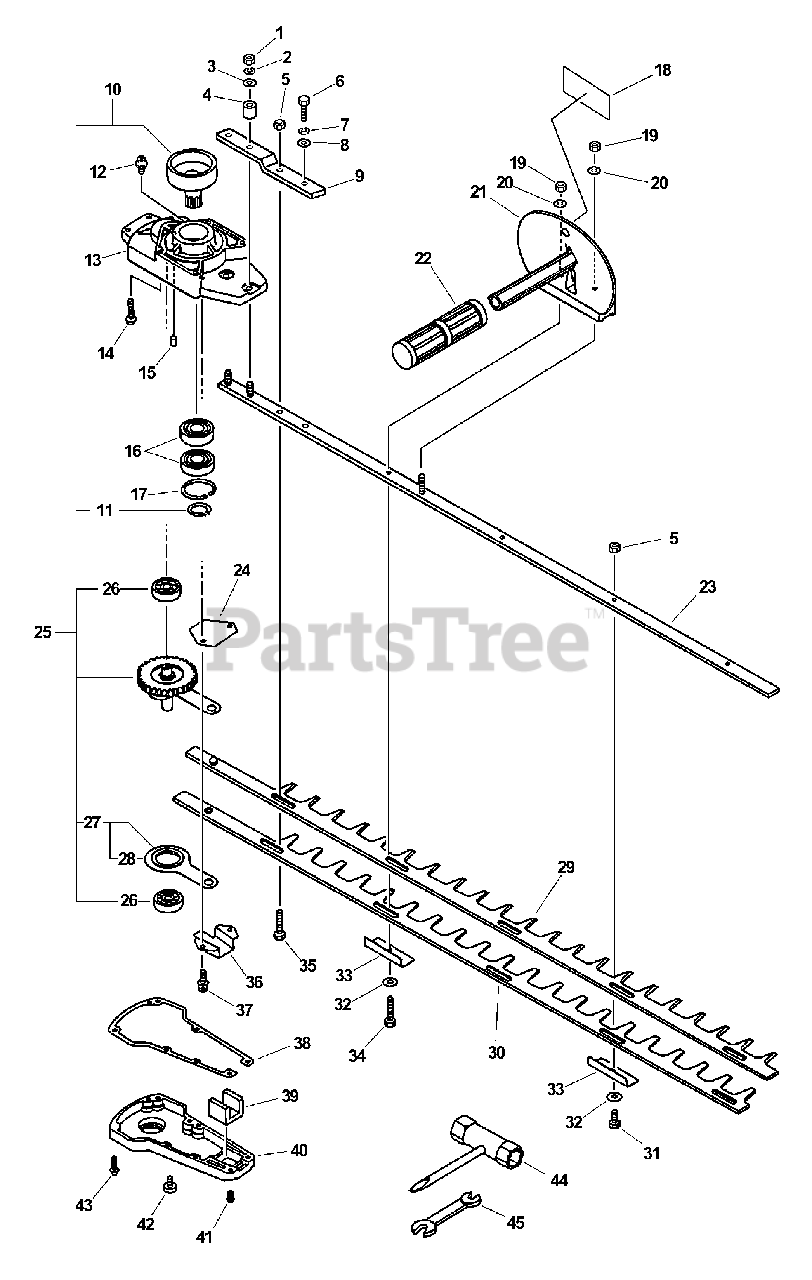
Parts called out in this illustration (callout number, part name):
1	NUT, HEX M6
2	WASHER, SPRING 6
3	WASHER 6.5×11.5×0.8
4	SPACER
5	NUT M6
6	BOLT 6×10
7	WASHER, SPRING 6
8	WASHER 6.5×11.5×0.8
9	BRACKET, BLADE
10	DRUM, CLUTCH
11	RING, RETAINING - 16
12	FITTING, GREASE
13	CASE, GEAR
14	BOLT 5×30
15	PIN, LOCATING 4
16	BEARING, BALL 6003
17	RING, SNAP 35
18	LABEL, CAUTION
19	NUT, LOCK 6
20	WASHER 6.5×13×1
21	BRACKET ASSY
23	BAR, FRAME
24	GUIDE
25	GEAR ASSY
26	BEARING, BALL 6200
27	CONNECTING ROD ASSY
28	BEARING, NEEDLE
29	BLADE - UPPER
30	BLADE - LOWER
31	BOLT 6×22
32	WASHER
33	INSULATOR
34	BOLT 6×40
35	BOLT 6×25
36	GUIDE
37	BOLT 5×14
38	GASKET, GEAR CASE
40	LID, GEAR CASE
41	SCREW 4×14
42	BOLT 8×8 SP
43	SCREW 4×22
44	T-WRENCH 13×19×180
45	SPANNER 8×10
